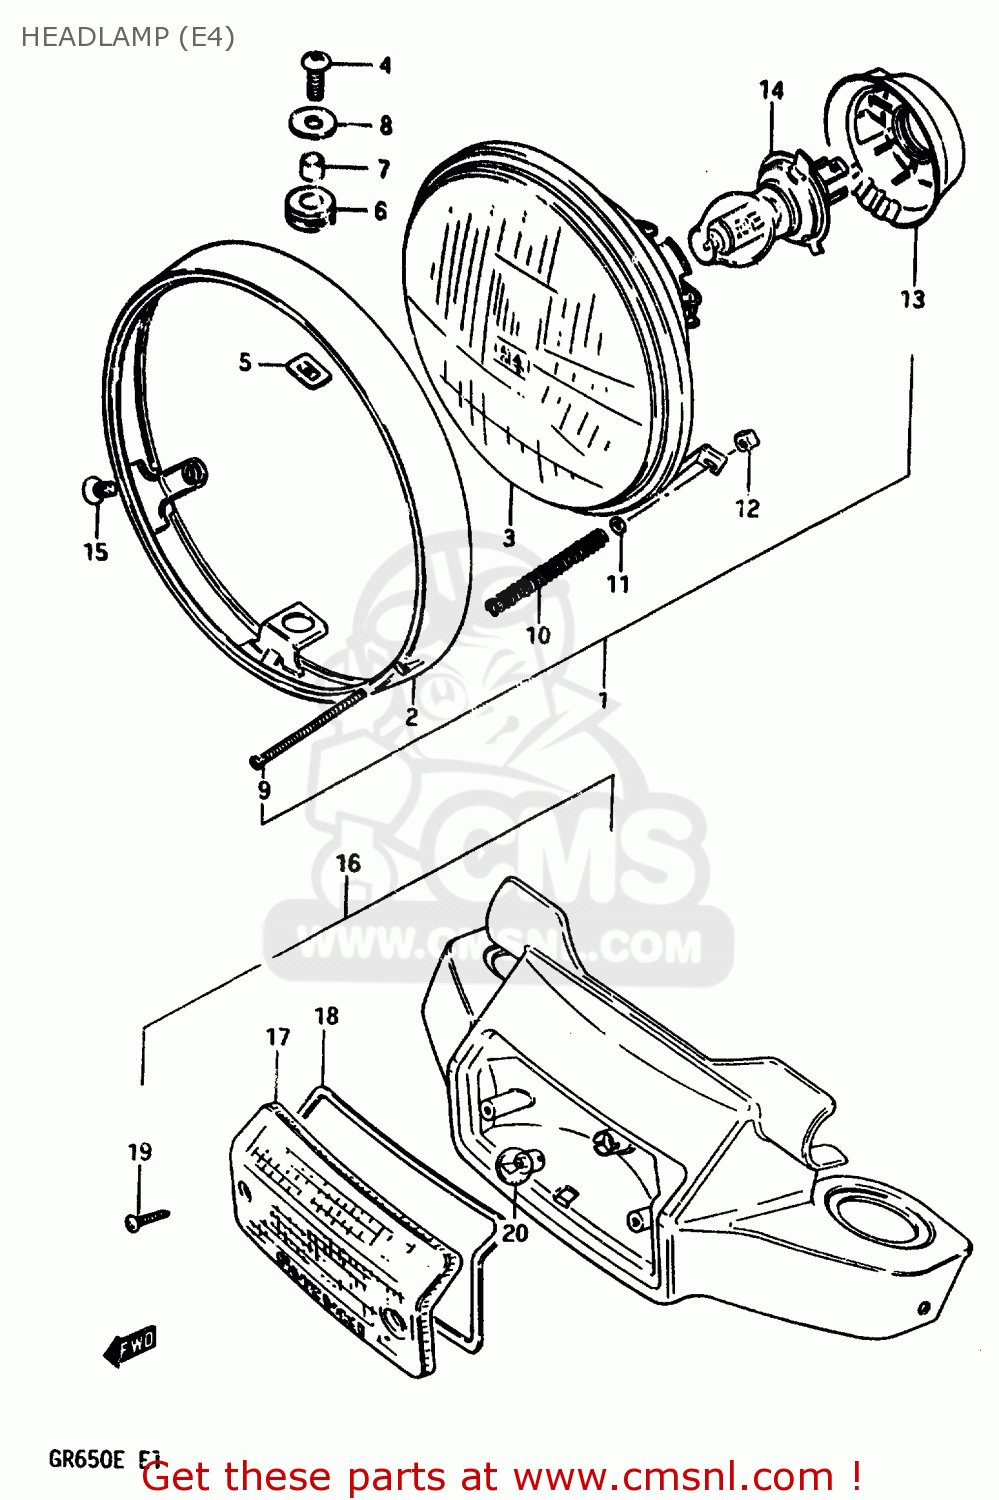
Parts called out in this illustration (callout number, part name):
1	HEADLAMP ASSY
2	RIM,HEAD LAMP
3	UNIT
4	SCREW(5X14)
5	NUT
6	CUSHION
7	SPACER
8	WASHER
9	SCREW,HEADLAMP ADJUST
10	SPRING,HEADLAMP ADJUST
11	WASHER
12	NUT
13	COVER,SOCKET
14	BULB (12V, 60/55W, H4)
15	SCREW(5X12)
16	LAMP ASSY, FRONT POSITION
17	LENS
18	GASKET,POSITION LAMP
19	SCREW,POSITION LENS
20	BULB(12V4W)
